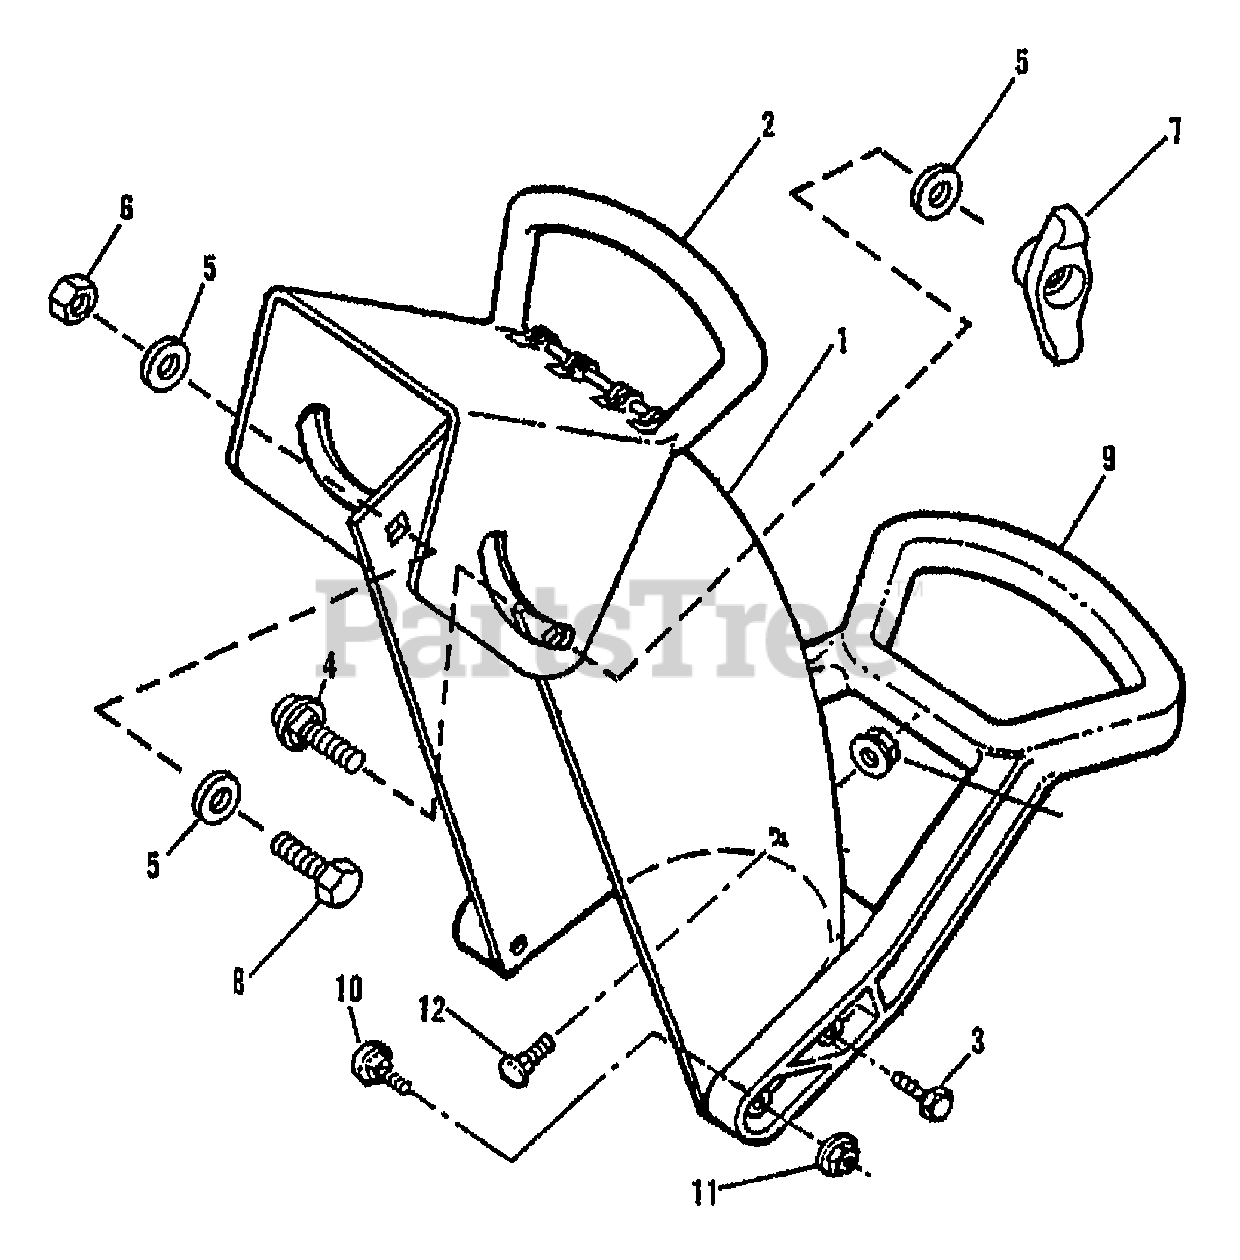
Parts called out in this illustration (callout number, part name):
1	CHUTE-DISCHARGE W/DECALS
2	DEFLECTOR-CHUTE W/DECALS
3	SCR-HH 5/16-18X.75
4	SCR-CARR 5/16-18X1
5	WASHER-FLAT 5/16
6	NUT-CTR LK 5/16-18
7	KNOB-CHUTE DEFLECTOR
8	SCR-HH 5/16-24X.75
9	HANDLE-CHUTE CONTROL
10	SCR-CARR 5/16-18X1.25
11	NUT-HFLK 5/16-18
12	SCR-CARR 5/16-18X.75
